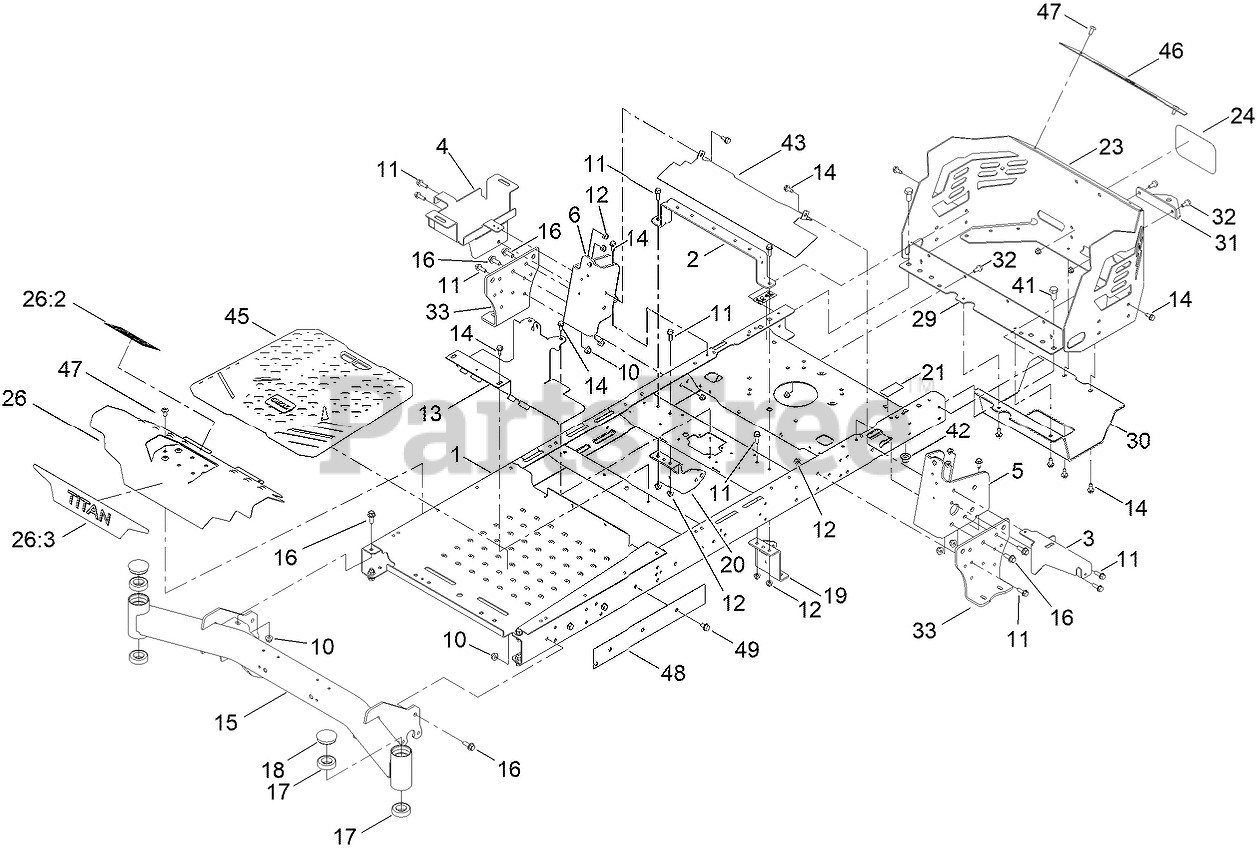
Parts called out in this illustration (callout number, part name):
1	FRAME ASM
2	BRACE-SEAT, REAR (WIDE)
3	BRACKET-SUPPORT, POD (LH)
4	TRAY-BATTERY
5	BRACKET-MOUNTING, LH
6	BRACKET-MOUNTING, RH
10	NUT-HF, NI
11	SCREW-HHF
12	NUT-HF, NI
13	BRACKET-MOUNT
14	SCREW-HWHTF
15	FRONT AXLE ASM
16	SCREW-HHF
17	BEARING-BALL
18	CAP-GREASE
19	MOUNT-HYDRO, FRONT (LEFT)
20	MOUNT-HYDRO, FRONT (RIGHT)
21	DECAL-BYPASS
23	GUARD-ENGINE
24	DECAL
26	FOOTREST-TITAN
26:2	DECAL-DANGER
26:3	DECAL-TITAN
29	CROSSMEMBER-REAR, WIDE
30	GUARD-MUFFLER
31	BRACKET-HITCH
32	SCREW-HHF
33	MOUNT-HYDRO
41	SCREW-HH
42	NUT-LOCK
45	FLOOR MAT
46	TRIM-GUARD, ENGINE
48	PLATE-FRAME
49	SCREW-HWHTF
